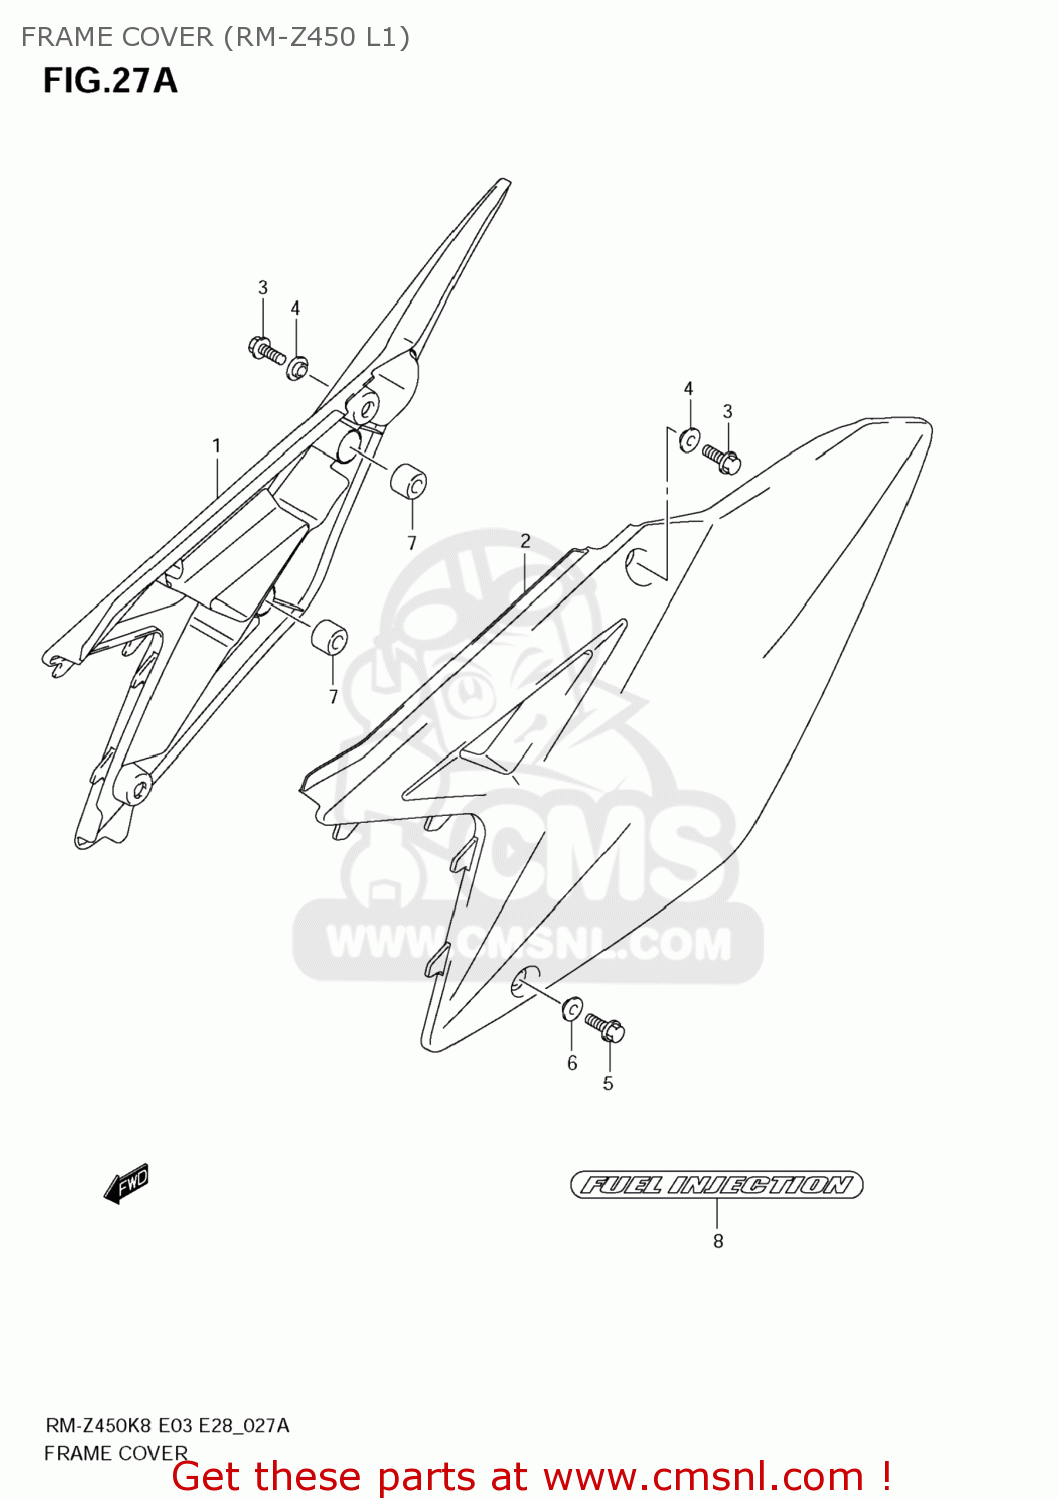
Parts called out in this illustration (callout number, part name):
1	COVER,FRAME,R(WHITE)
2	COVER,FRAME,L(WHITE)
3	BOLT
4	WASHER
5	BOLT(6X16)
6	WASHER
7	CUSHION
8	EMBLEM,FRAME COVER
